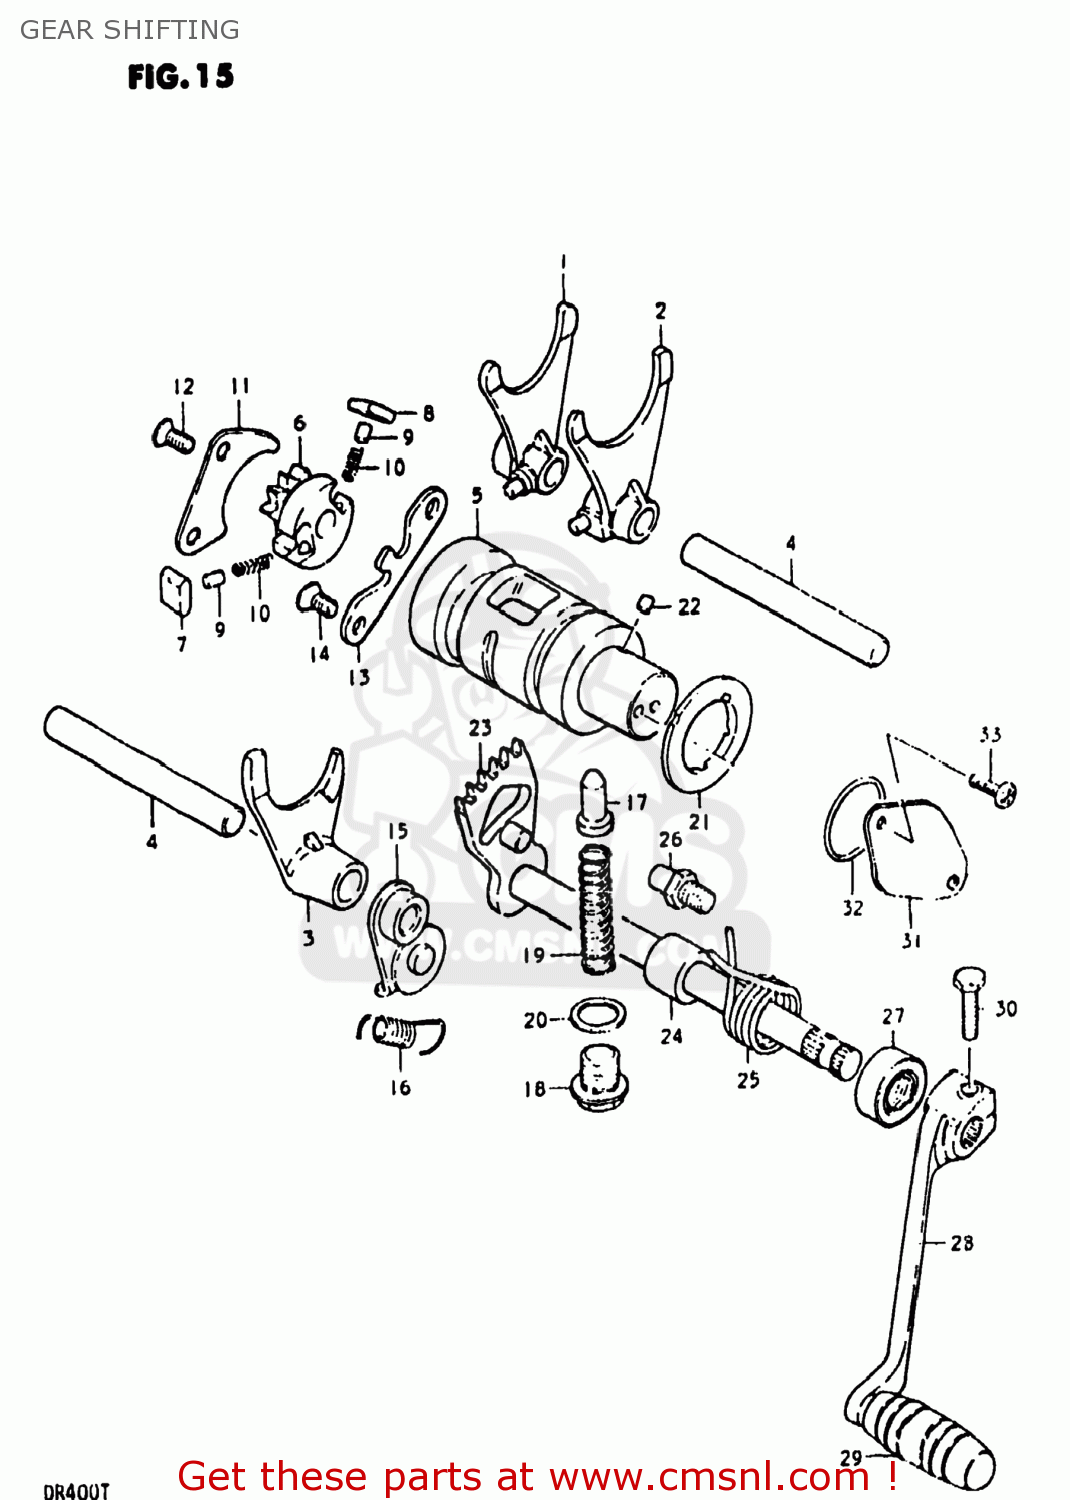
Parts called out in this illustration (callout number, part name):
1	FORK,GEAR SHIFT NO.1
2	FORK,GEAR SHIFT
3	FORK,GEAR SHIFT NO.3
4	SHAFT,GEAR SHIFT FORK
5	CAM,GEAR SHIFT
6	RETAINER,GEAR SHIFT CAM
7	PAWL,GEAR SHIFT NO.1
8	PAWL,GEAR SHIFT NO.2
9	PIN(5X8)
10	SPRING
11	LIFTER,GEAR SHIFT PAWL
12	SCREW
13	GUIDE,GEAR SHIFT CAM
14	SCREW
15	STOPPER,GEAR SHIFT CAM
16	SPRING
17	STOPPER,GEAR SHIFT CAM NO.2
18	PLUG
19	SPRING
20	GASKET(14X19.2X2) (NAS)
21	PLATE,GEAR SHIFT CAM STOPPER
22	PIN 4X6
23	SHAFT,GEAR SHIFT
24	SPACER(12X20X15.3)
25	SPRING
26	STOPPER,GEAR SHIFT CAM
27	OIL SEAL
28	LEVER ASSEMBLY,GEAR SHIFTING
29	RUBBER,GEAR SHIFT PEDAL
30	BOLT
31	CAP,GEAR SHIFT CAM PIVOT
32	O-RING (D:2.4 ID:26.2)
33	SCREW
